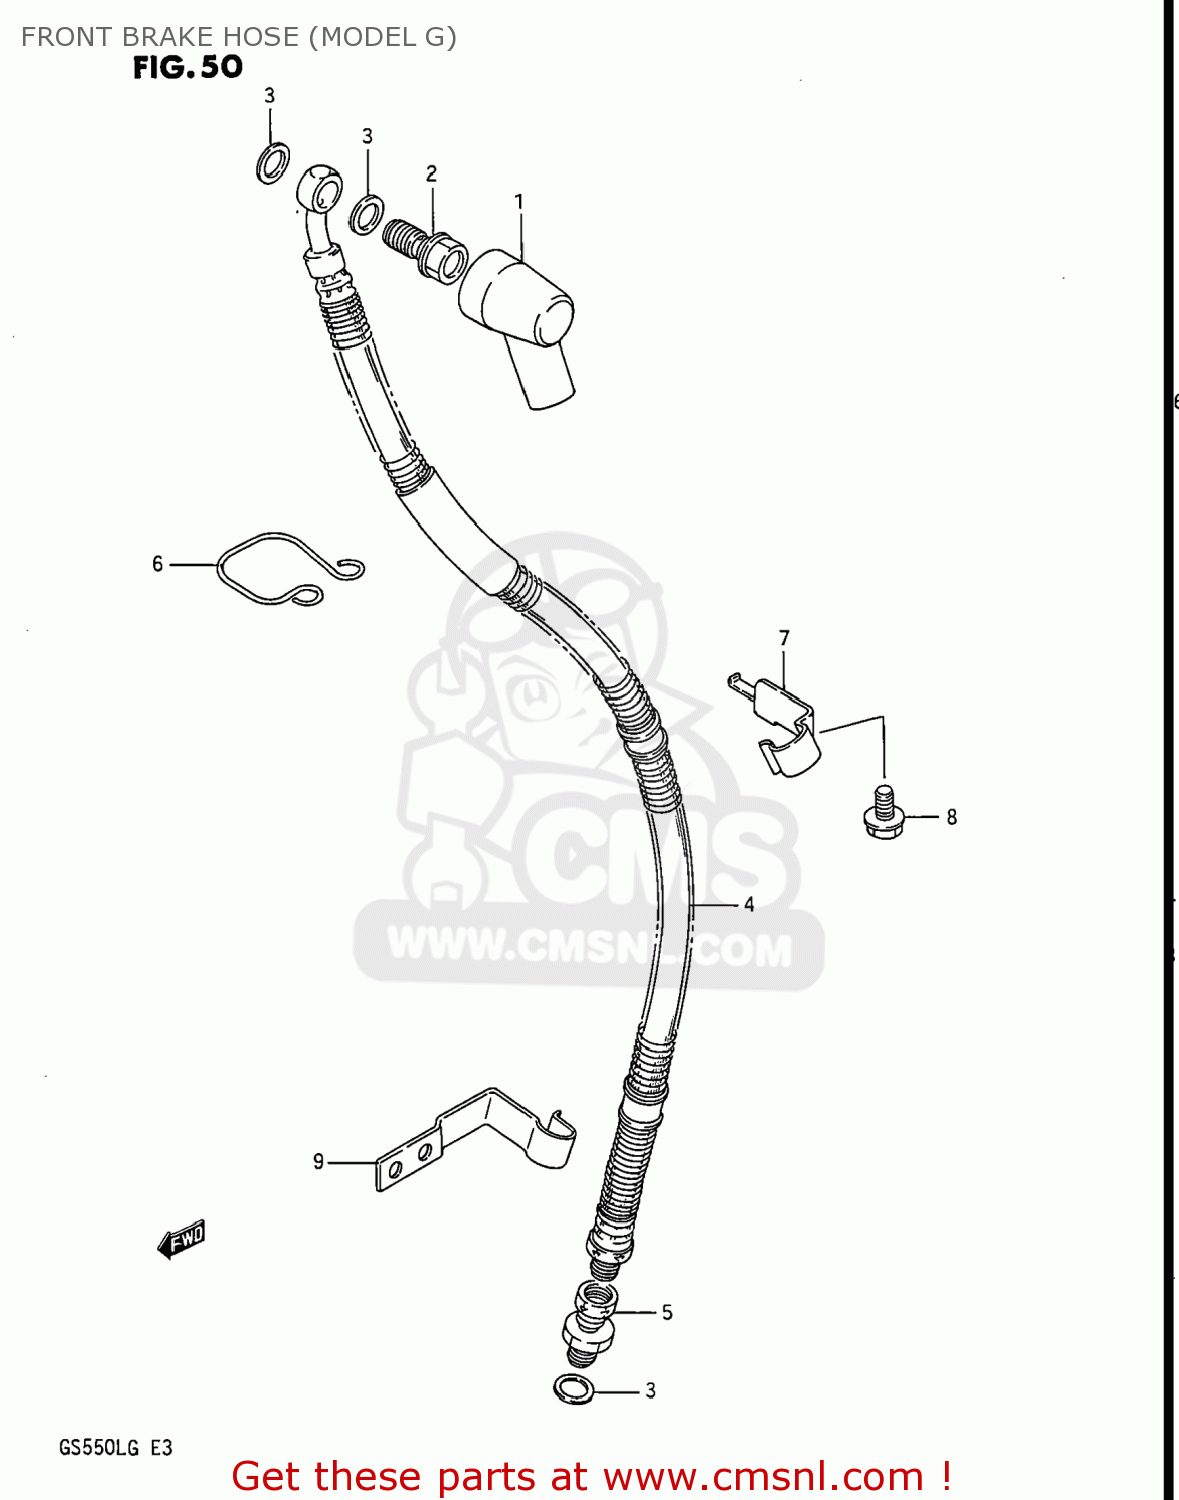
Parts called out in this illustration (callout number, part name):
1	BOOT,MASTER CYLINDER
2	BOLT UNION
3	WASHER(10X15X1.5)
4	HOSE,FRONT BRAKE
5	ADAPTER,BRAKE HOSE
6	GUIDE,CABLE/HARNESS
7	GUIDE
8	BOLT
9	GUIDE,BRAKE HOSE NO.2
